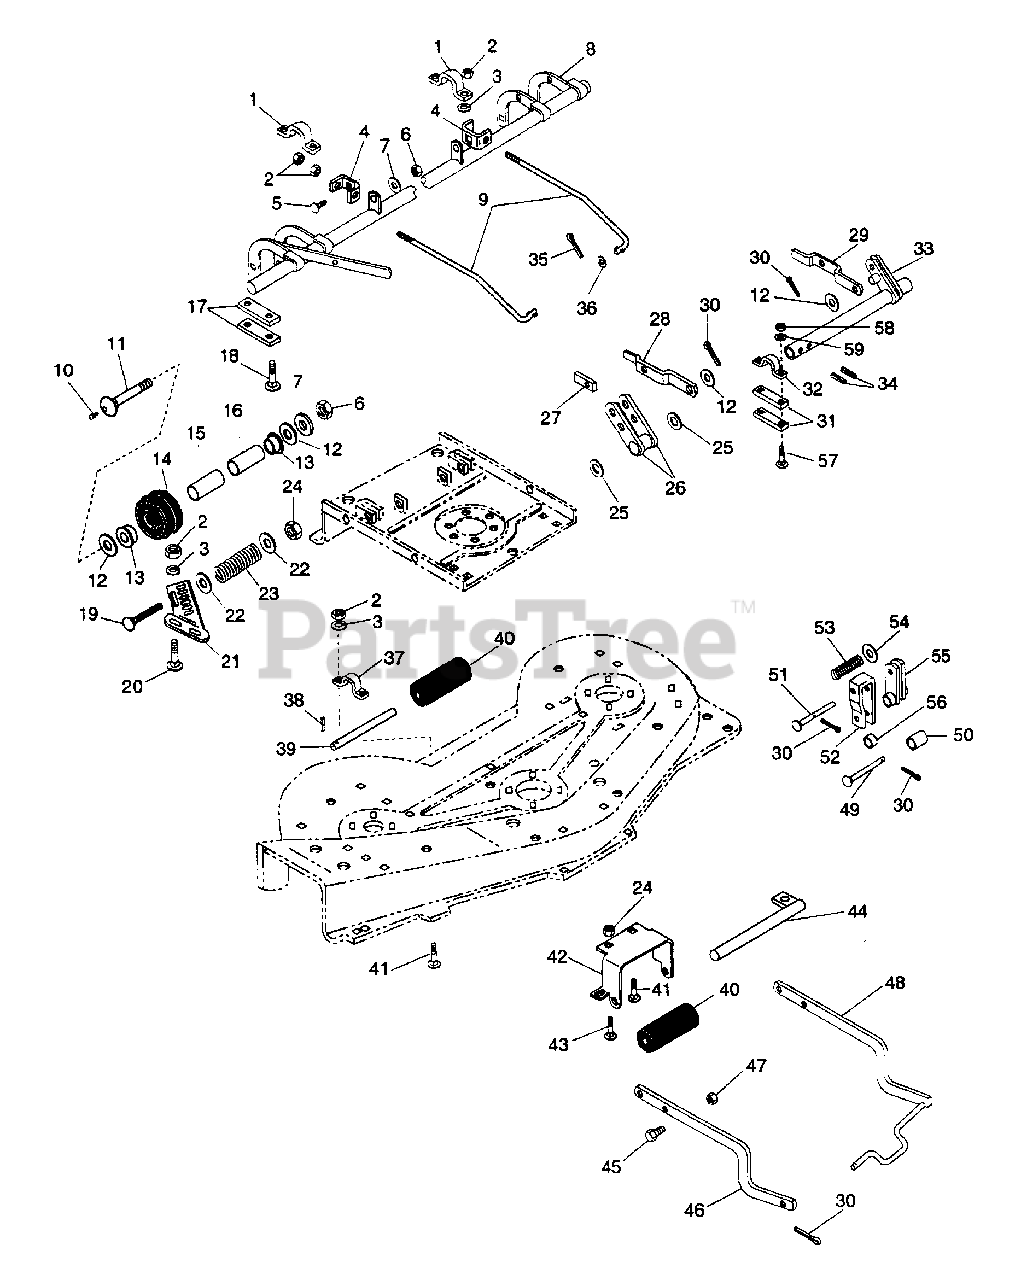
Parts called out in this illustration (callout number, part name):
1	CLAMP
2	NUT-HEX .312-18
3	WSHR-LK .312X.097 PL HVY
5	BLT-RDHDSQNK .50-13X1.25 PL
6	NUT-LK-CTR .50-13
7	WSHR-FL-STL .505X.880X.072 PL
8	ROLLER FRAME
9	ADJUSTMENT ROD
10	FTG-LUBE .25-28X.256 YWZC
11	WHEEL BOLT W/ZERK
12	WSHR-FL-STL .511X1.441X.125 PL
13	BRG-BALL .500X1.125X.500
14	WHL 5 IN O.D.
15	WHEEL HUB
16	SPACER .512X.747X3.396
17	PAD
18	BLT-RDHDSQNK .31-18X1.00 PL
19	BLT-RDHDSQNK .31-18X1.75 PL
20	BLT-RDHDSQNK .25-20X.75 GR5PL
21	QUADRANT
22	WSHR-FL-STL .38X.875X.083 PL
23	SG-COMP .063X.53X1.187
24	NUT-LK .312-18 GR A PL
25	WSHR-FL-STL .781X1.250X.059 PL
26	FRONT HANGER LINK
27	WEAR PLATE
28	LEVELING LEVER R.H.
29	LEVELING LEVER L.H.
30	PIN-COTR .12X1.0 PL
33	FRONT HANGER
34	PIN-ROLL .250X1.25
35	PIN-COTR .12X.75 PL
36	WSHR-FL-STL .469X.937X.065 PL
37	ROLLER CLAMP
38	PIN-ROLL .250X1.00
41	BLT-RDHDSQNK .31-18X.75 GR5 PL
42	BRACKET, ROLLER
43	BLT-RDHDSQNK .312-18X.62 PL
44	ROLLER SHAFT
45	BLT-HEX .38-16X1.00 PL GR5
46	HANGER ARM
47	NUT-LK-CTR .375-16 GR A PL
48	MOWER HANGER
49	PIN-CLEV .498X4.50 YWZC
50	SPACER .390X1.000X.562
51	PIN-CLEV .498X4.31 YWZC
52	SUPPORT CHANNEL
53	SG-COMP .62X.68X1.75
54	WSHR-FL-STL .531X1.062X.095 PL
56	SPACER .516X.749X.938
57	BLT-RDHDSQNK .50-13X1.50 PL
58	NUT .50-13 PL
59	WSHR-LK .500X.151 HVY PL
